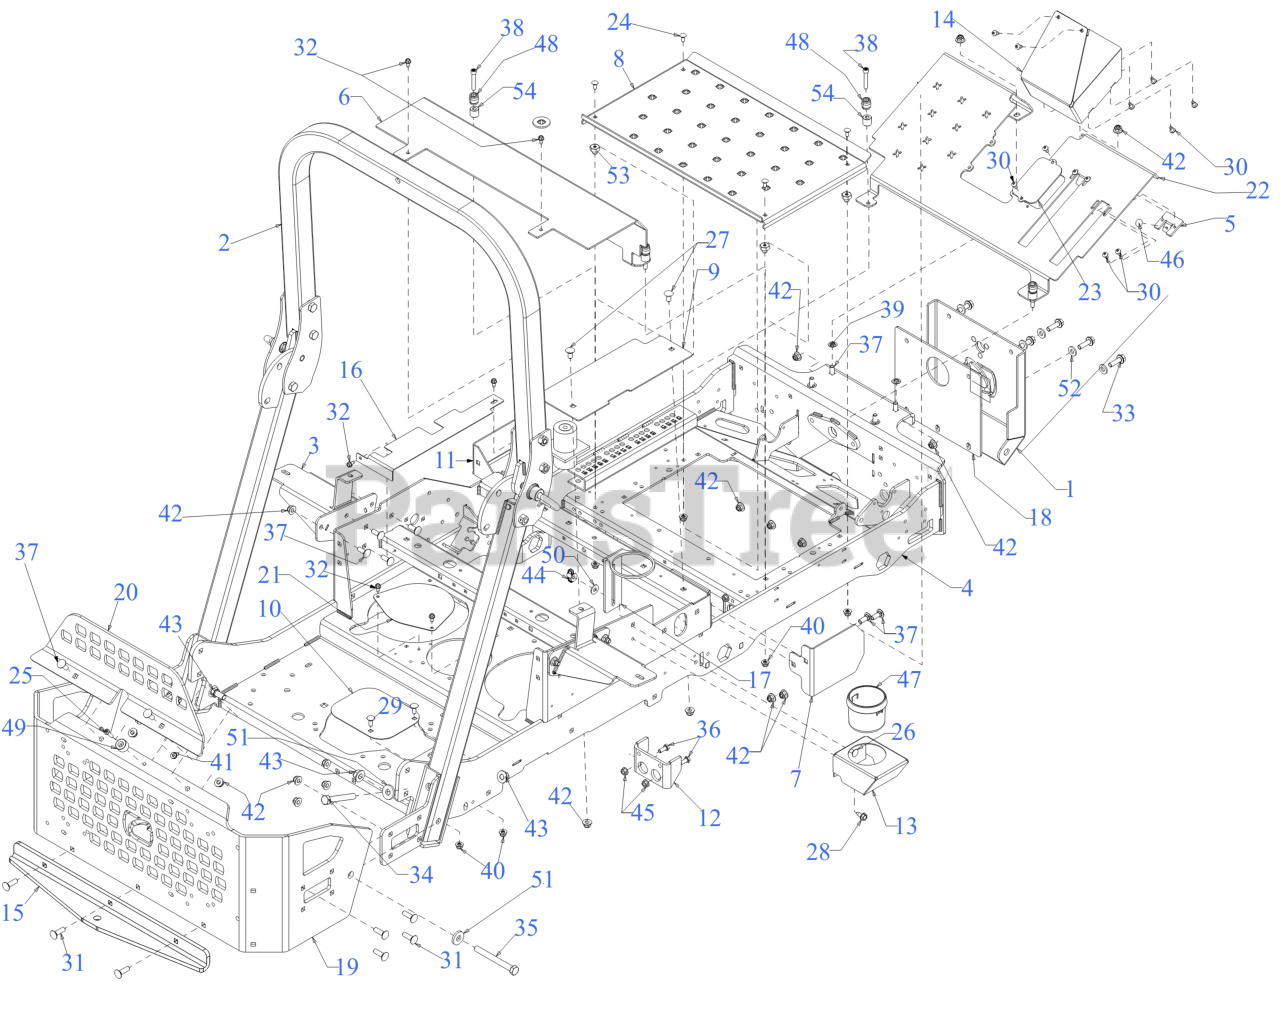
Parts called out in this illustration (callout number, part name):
2	PRO Z ROPS KIT
3	FUEL TANK MOUNT
4	FRAME
5	REVERSE PEDAL STOP BRACKET
6	SEAT BOX COVER
11	SEAT BOX END COVER (LH)
12	FRONT DECK LIFT MOUNTING BRACKET
13	LOWER CUP HOLDER
18	FRONT MOUNTING PLATE SPACER
19	BUMPER (REAR)
20	BUMPER (UPPER RR)
21	FRAME COVER PLATE
22	FRONT PEDAL COVER
23	SERVICE DOOR
24	CARRIAGE BOLT 1/4-20 x .62
25	MACHINE SCREW 1/4-20:1
26	CARRIAGE BOLT 5/16-18 x 1.00
27	CARRIAGE BOLT 3/8-16 x .750 GR5
28	SCREW 5/16-18 x .750
29	CARRIAGE BOLT 5/16-18 x .75
30	SCREW 1/4-20 x .5
31	CARRIAGE BOLT 3/8-16 X1.25 GR5
32	SCREW 1/4-20 X.500
33	SCREW 3/8-16 x 1.25 GR5
34	HEX SCREW 1/2-13 x 3.50
35	SCREW 1/2-13 x 4.5 GR 5
36	SCREW 5/16-18 x .75 GR5
37	CARRIAGE BOLT 3/8-16 x 1.00 GR5
38	SCREW 5/16-18X1.75 GR5
40	FLANGE LOCK NUT 5/16-18
41	FLANGE LOCK NUT
44	WING NUT 5/16-18
45	HEX FLANGE NUT
46	RATCHET CLIP
48	RADIAL BUMPER
50	FLAT WASHER
51	FLAT WASHER .531 x 1.25 x .181
52	FLAT WASHER
53	SHOULDER SPACER
